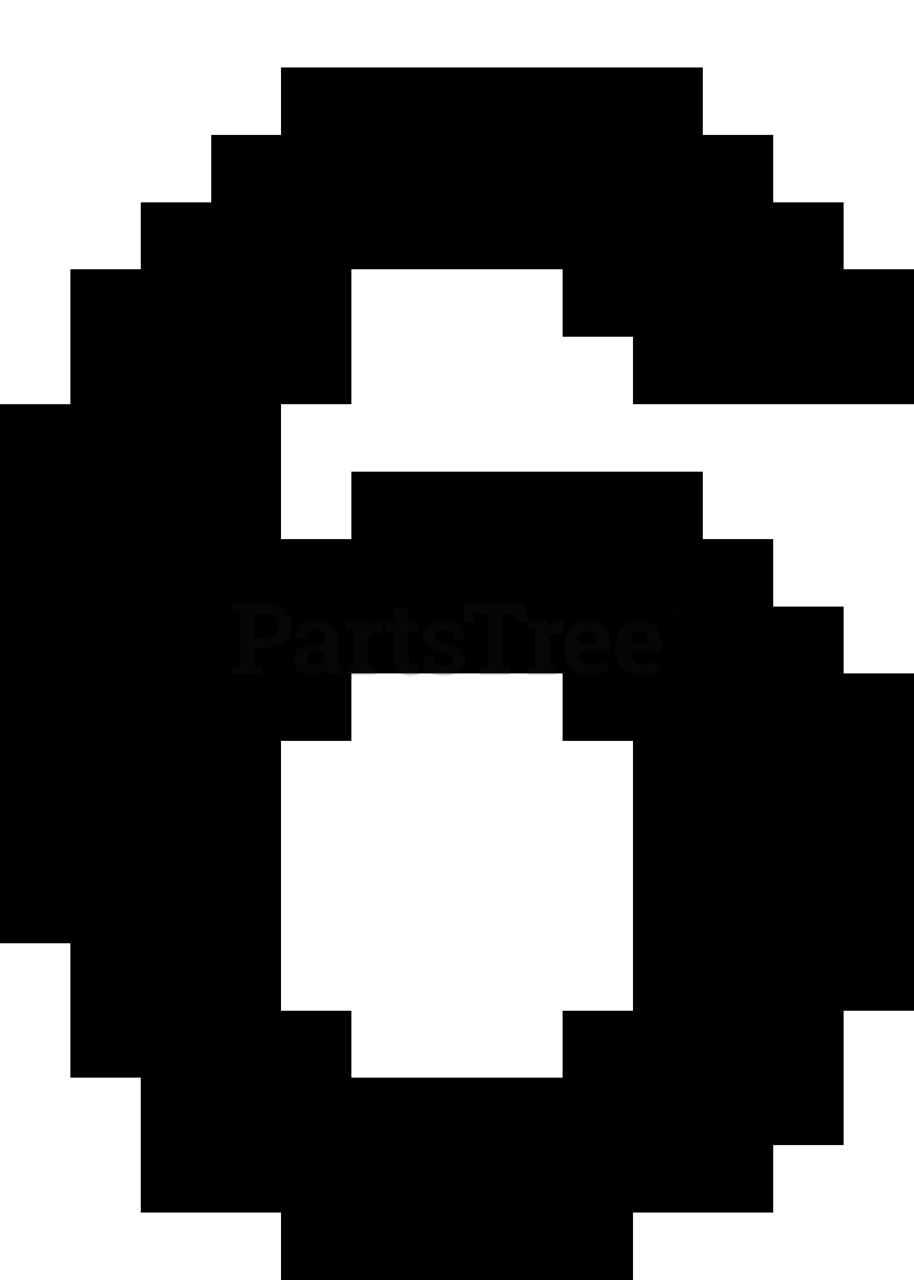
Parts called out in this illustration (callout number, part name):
1	TRANSMISSION K574A
3	WASHER BRB 8.4X17
4	NUT
5	SCREW
11	LOCKNUT M5
15	BELT TENSIONER ARM
17	SCREW
19	LOCKNUT M8
25	HOSE CLAMP 20-32
26	BRACKET
27	NUT
